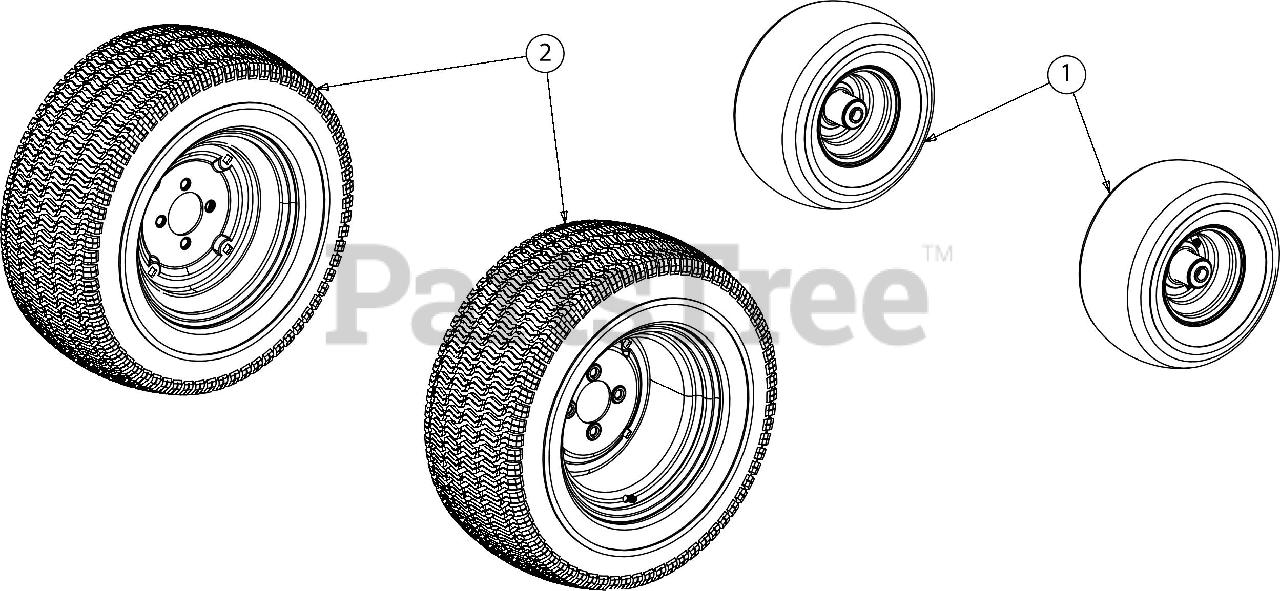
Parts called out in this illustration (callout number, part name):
1	WHEEL ASSEMBLY (13 X 6.50-6)
1	TUBELESS VALVE
1	GREASE FITTING
1	BRG-BALL .754 ID X 1.750 OD
2	WHEEL ASSEMBLY (23 X 10.5 X 12)
2	TUBELESS VALVE
2	TIRE 23X10.5X12 TURF MSTR
